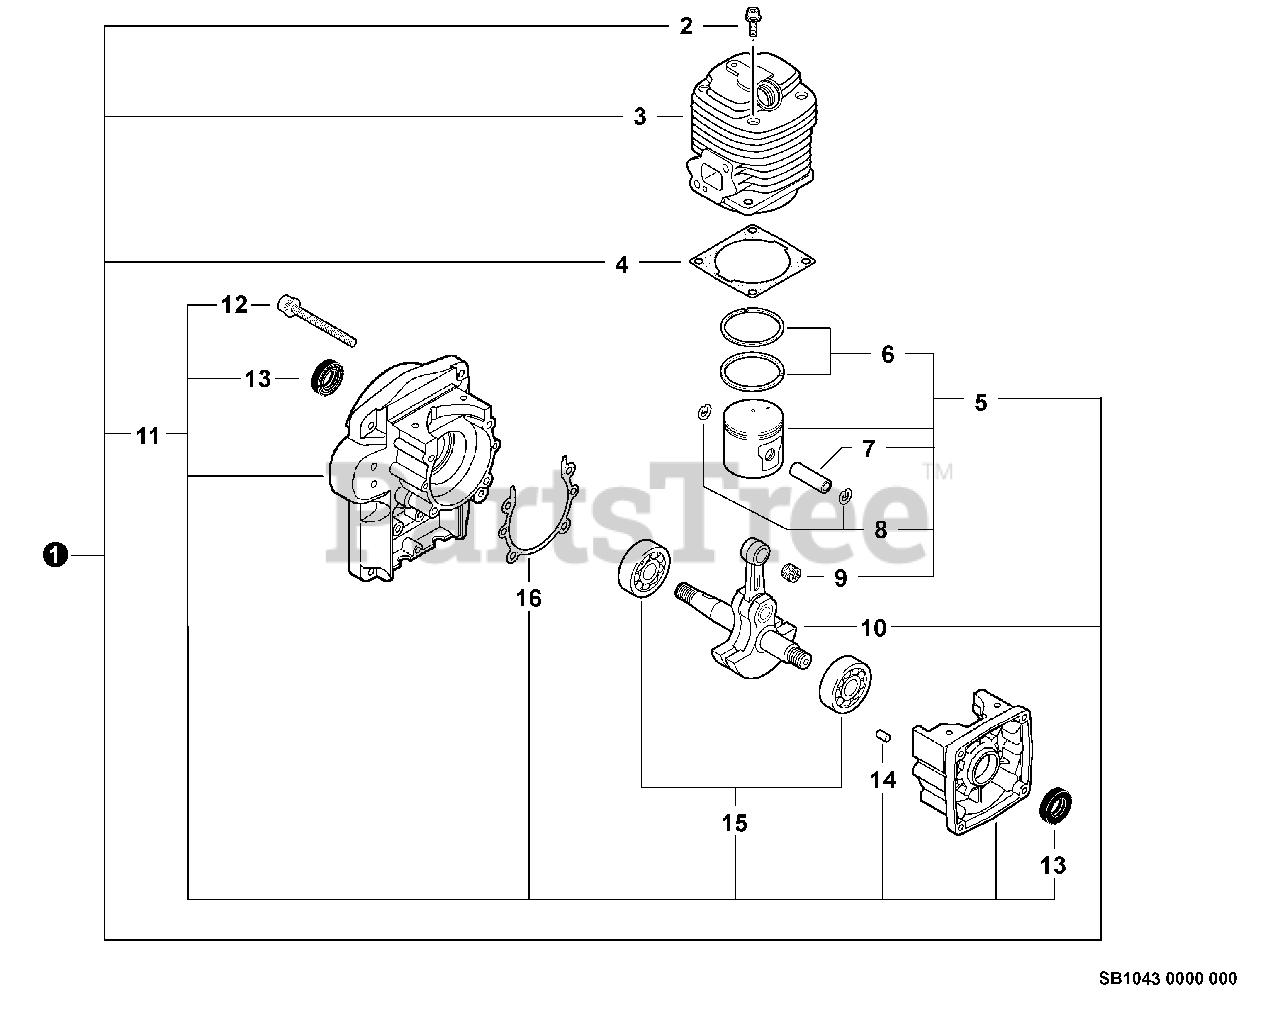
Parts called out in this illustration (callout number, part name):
1	SHORT BLOCK -- SB1043
2	SCREW - 5X22
3	CYLINDER
4	GASKET, CYLINDER
5	PISTON KIT
6	RING, PISTON
7	PIN, PISTON
8	RING, RETAINING - 8
9	BEARING, NEEDLE
10	CRANKSHAFT ASSY
11	CRANKCASE KIT
12	SEAL, OIL
13	PIN - LOCATING
14	BEARING, BALL - 6202
15	GASKET, CRANKCASE
16	SCREW - 5X40
